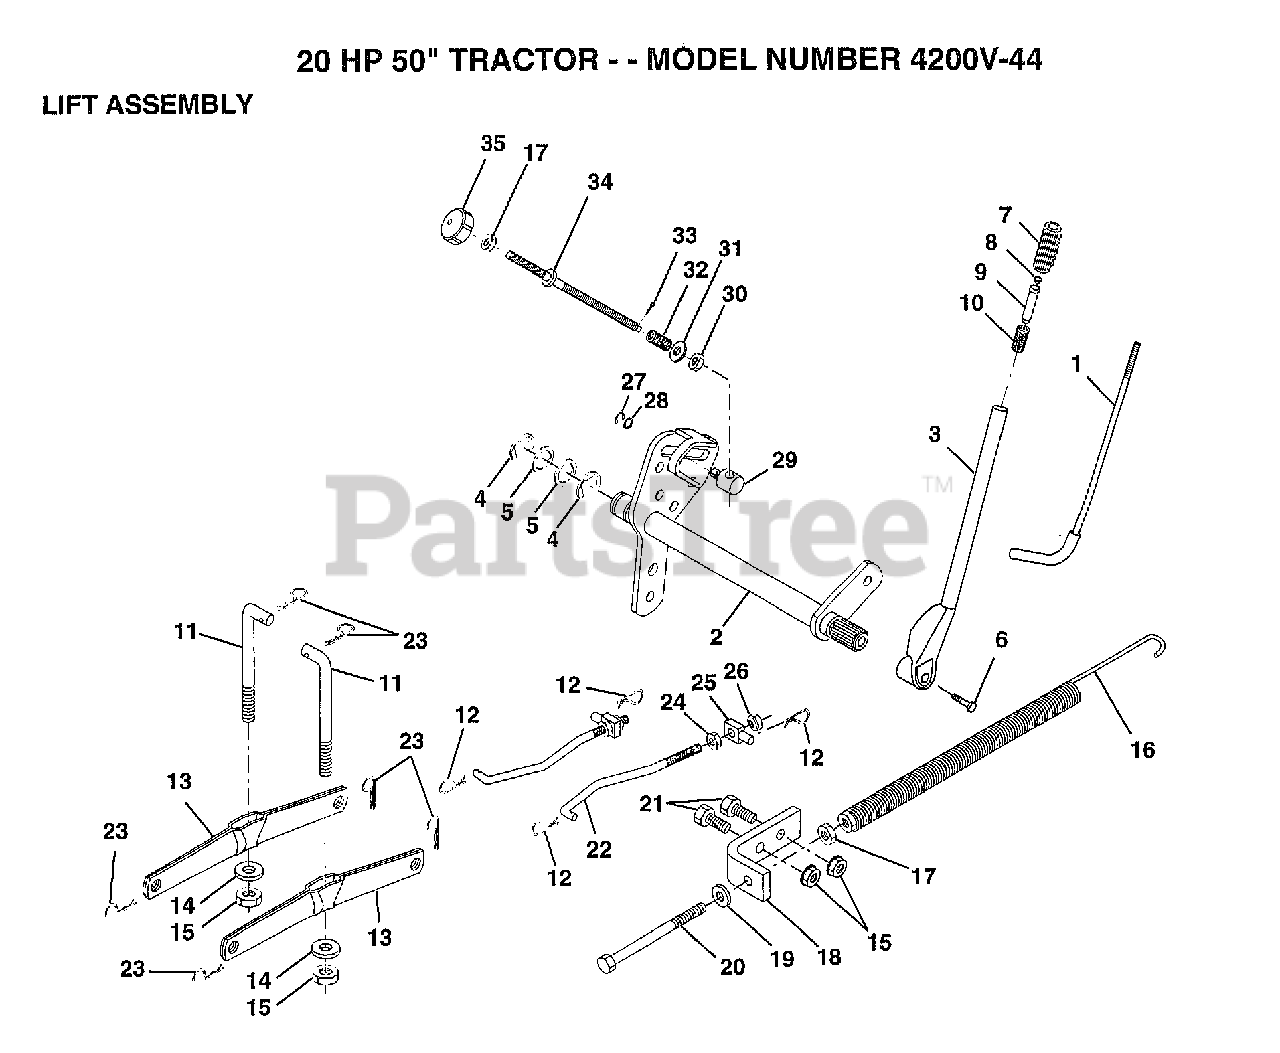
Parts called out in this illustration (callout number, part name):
1	LEVER ROD LT
4	E-RING
5	WASHER
6	"BOLT,HEX"
7	GRIP
10	SPRING T
12	RETAINER.SPRING
14	BEARING PVT LH
15	NUT
17	NUT
18	BRACKET SPRING AS
19	WASHER
20	BOLT-ADJ SPRING T
21	BOLT
22	LINK.FRONT
24	NUT
25	TRUNION
26	NUT.LK.W/WSH.1/2.
27	KLIP RING
28	WASHER
29	TRUNION LT
30	NUT T
31	WASHER
32	SPRING.COMP.INF.H
34	ROD.ADJ.LIFT
35	KNOB INF 3/8-16
